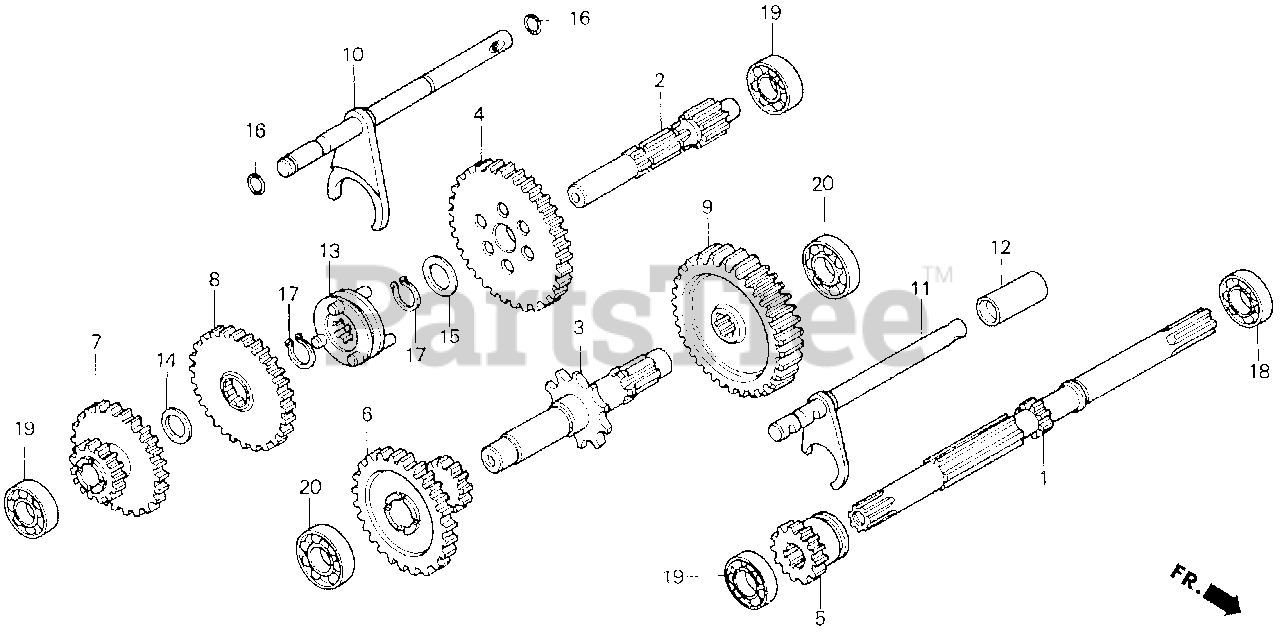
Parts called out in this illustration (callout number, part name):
1	SHAFT, INPUT
2	COUNTERSHAFT
3	SHAFT, FINAL
4	GEAR, COUNTERSHAFT FIRST (56T) (NOT AVAILABLE)
5	GEAR, CHANGE (22T)
6	GEAR, REVERSE IDLE (23T-49T) (NOT AVAILABLE)
7	GEAR, FIRST IDLE (45T-23T) (NOT AVAILABLE)
8	GEAR, REDUCTION DRIVEN (48T) (NOT AVAILABLE)
9	GEAR, FINAL
10	COUNTERSHAFT, FORK (NOT AVAILABLE)
11	SHAFT, INPUT FORK (NOT AVAILABLE)
12	COLLAR, INPUT FORK SHAFT
13	SHIFTER, COUNTERSHAFT
14	WASHER, THRUST (15MM)
15	WASHER (18.2X26X1)
16	O-RING (8.8X1.9)
17	CIRCLIP (OUTER) (18MM) (NOT AVAILABLE)
18	BEARING, RADIAL BALL (6003)
19	BEARING, RADIAL BALL (6202)
20	BEARING, RADIAL BALL (6203)
